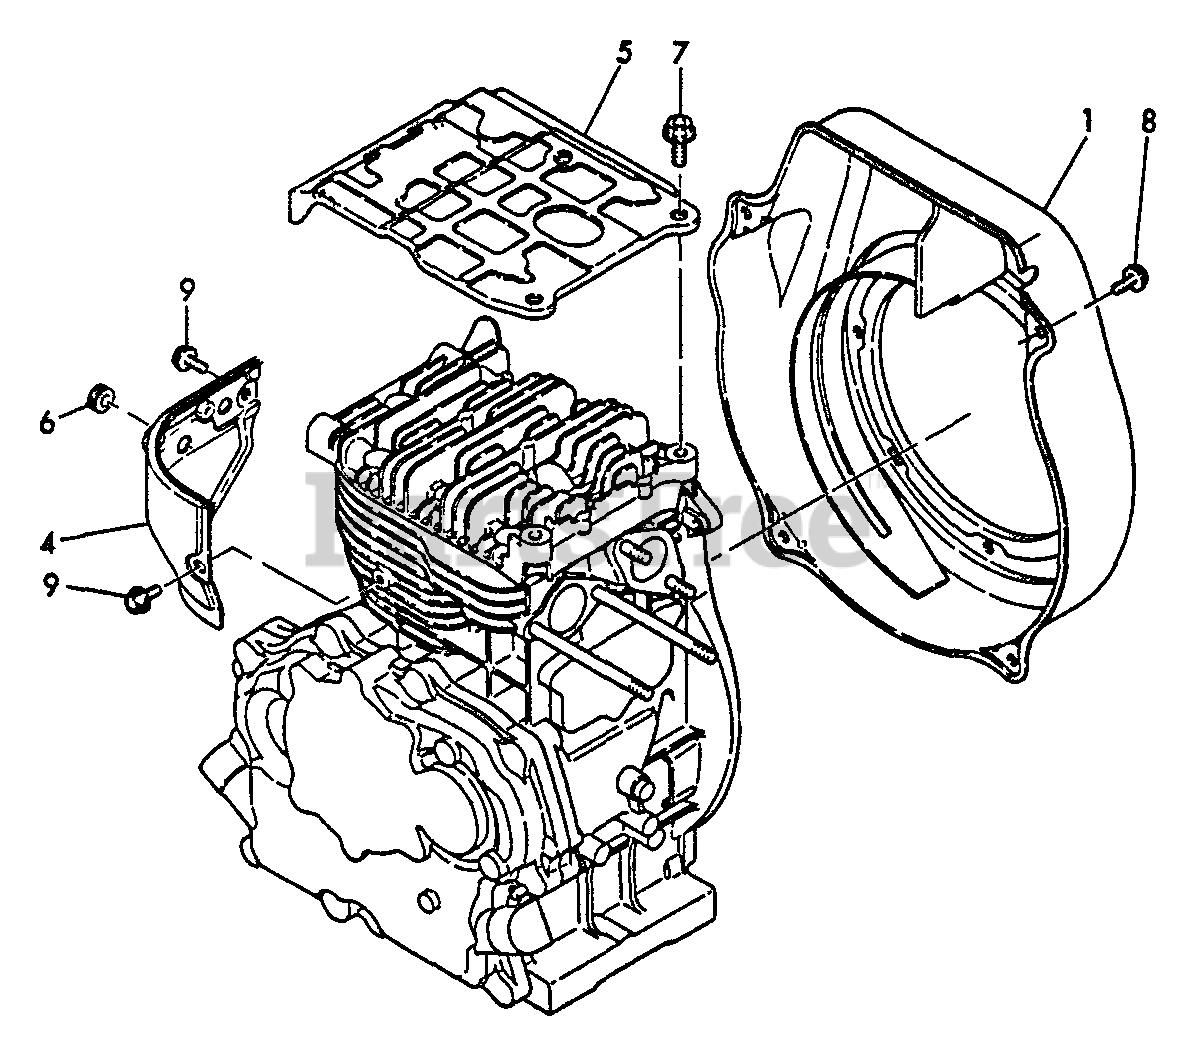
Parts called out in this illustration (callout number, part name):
1	COVER, FAN - INNER
4	SHIELD, CYLINDER
5	COVER, HEAD
6	GROMMET
7	BOLT - 8X20 -- PLATED
8	BOLT - 6X8 -- PLATED
9	BOLT - 6X8 -- PLATED
